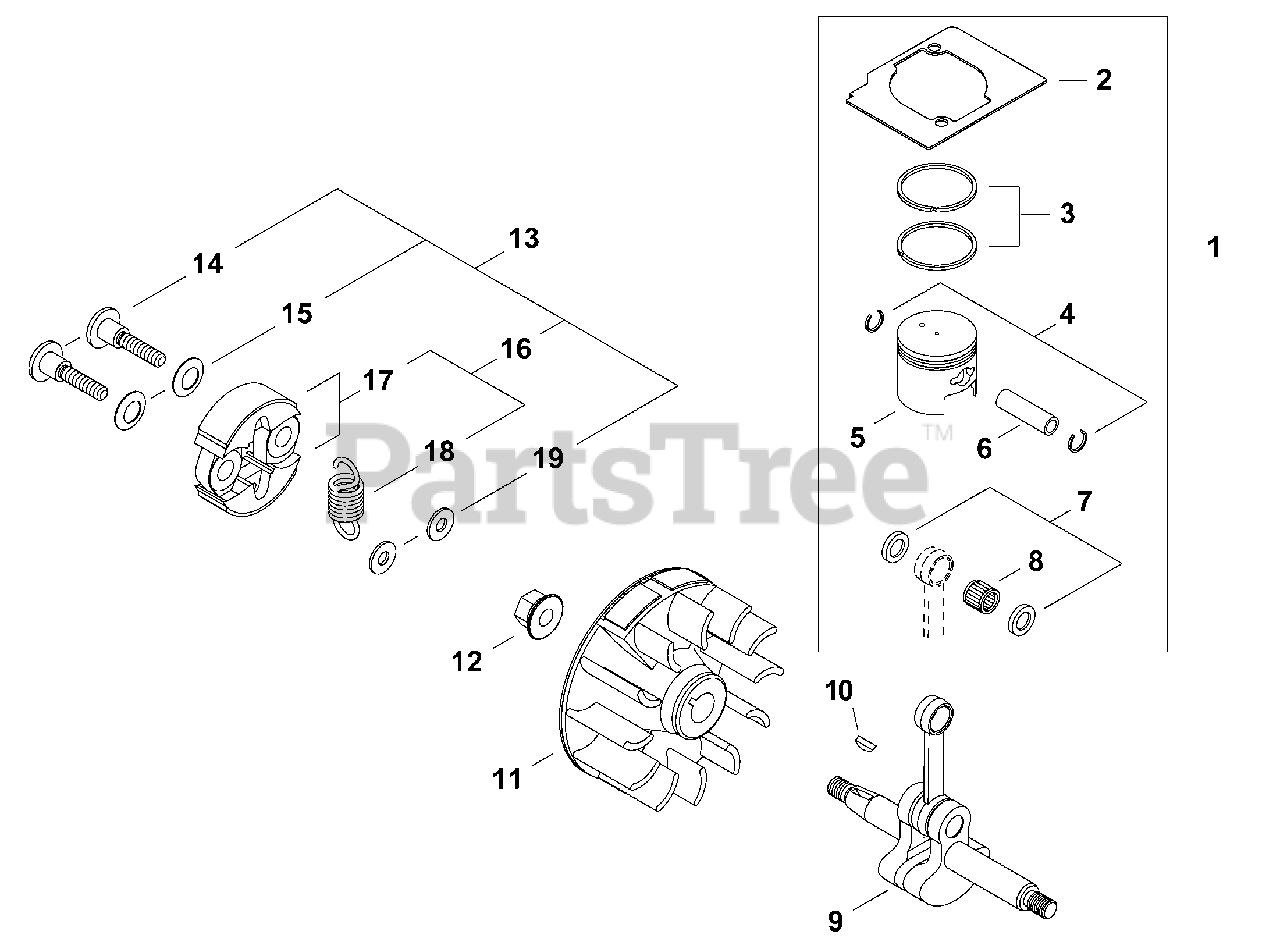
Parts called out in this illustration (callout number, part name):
1	PISTON KIT
2	GASKET, CYLINDER
3	RING, PISTON
4	RING, SNAP
6	PIN, PISTON 8
7	WASHER, THRUST 8
8	BEARING, NEEDLE 8
9	CRANKSHAFT
10	KEY, WOODRUFF 3×10
11	FLYWHEEL
13	CLUTCH ASSY
14	BOLT, CLUTCH
15	WASHER, SPRING
16	SHOE ASSY, CLUTCH
17	SHOE, CLUTCH
18	SPRING, CLUTCH
19	WASHER 6 MM
